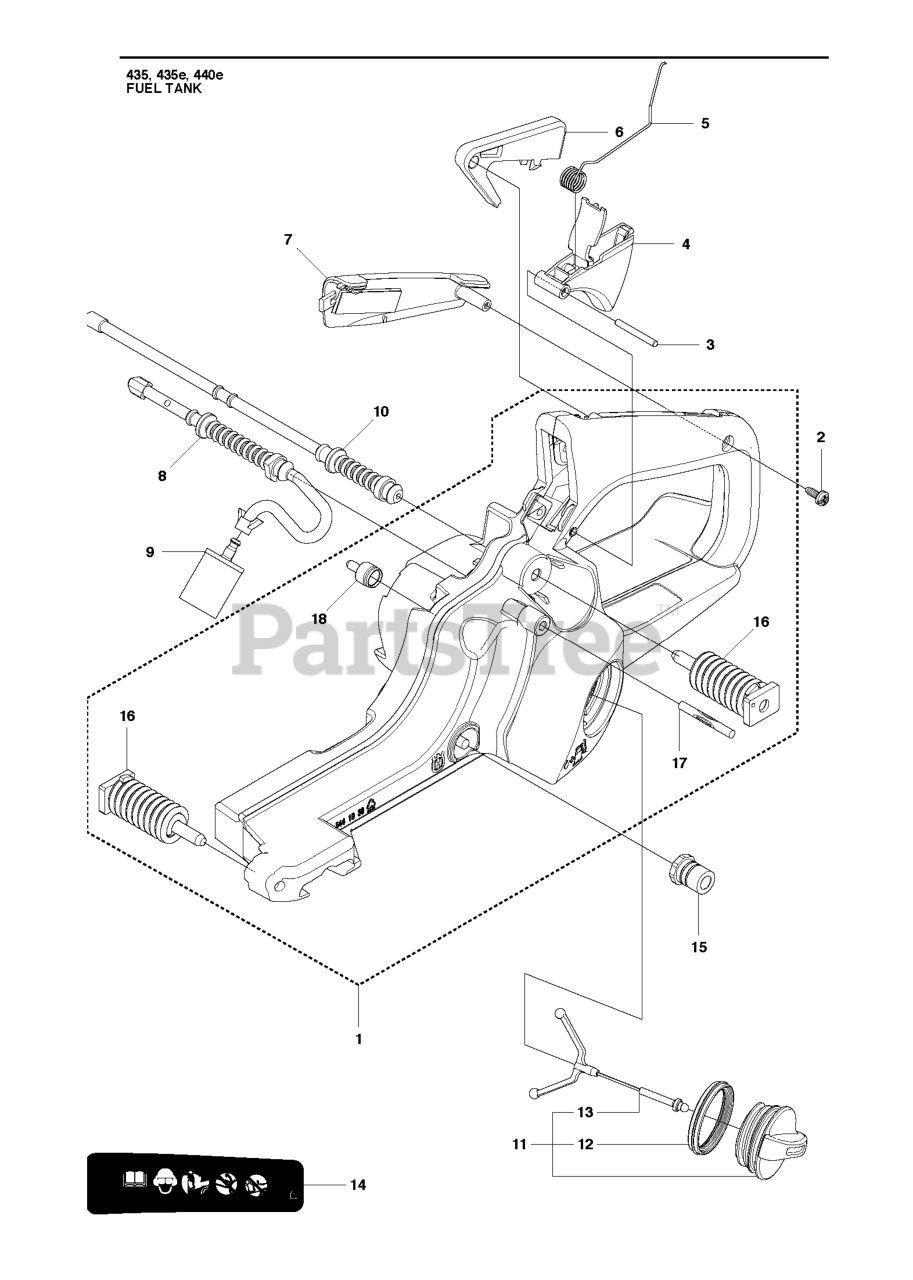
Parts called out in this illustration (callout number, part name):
1	DECK SVC 46"W/DECALS ORG
3	BLADE.MOWER.46".HI.LIFT
4	COVER.MANDREL.RH.46"
6	WHEEL.GAUGE.RALLY
7	BELT KEEPER 5"
8	PULLEY.IDLER.MWR.STATI.LH
9	PULLEY.IDLER.DECK
10	PULLEY.MANDREL.46"
11	SPRING.EXTENSION
12	SPRING, TORSION
13	ARM.PNT.CLTCHG.STMP.46.RZ.EDIP
14	COUPLING.QUICK CONNECT
15	PORT.WASHOUT
16	BAFFLE CENTER FRONT
17	BAFFLE FRONT RH
18	BRKT.DEFLECTOR.38"2005+
19	SHIELD.DEFLECTOR.MOWER.46"BLAC
20	MANDREL.W/SPCR.BRG.SHRT.NONRVL
21	IDLER BUSHING
22	BEARING.MANDREL.TOP.EXTENDED
23	SHAFT
24	ROD.HINGE
25	PLATE.REINFOR.46.SIDEBOLT.X431
26	PLATE.PNT.REINF.DECK.46".EDIP
27	NUT PUSH M
28	EYE BOLT 5/16 X 3.50
29	BOLT.5/16-18X1-1/4 FULL THD
30	BOLT.HEX.7/16-14
31	BOLT.SHOULDER.3/8-16X3-5/8.
32	SCREW.SEMS.7/16-20X1.HEX.HEAD
33	BOLT CARRIAGE
34	BOLT 5/16C X 3/4" CARRIAGE
35	SCREW.1/4-20X5/8
36	SCREW.BUTTONHEAD.1/4-20X1
37	SCREW #10 X 1/2 SELF TAPPING
38	BOLT.HEX.WASHR.HED.313-18X1.19
39	5/16-18 NYLOC FLANGE NUT
40	NUT.71038.31-18.HEX.NYLOCK
41	NUT T
42	NUT 5/16C WHIZ
43	NUT HEX 3/8-16 NYLON, THIN
44	NUT.FLANGE.LOCK.TOP
45	NUT.LOCK.FLANGE.7/16
46	NUT LOCK FLG 3/8-16 UNC
47	WASHER 5/16 FLAT
48	WASHER 7/16 FLAT ZD
49	WASHER 3/8 X 3/4 X .187 TK
